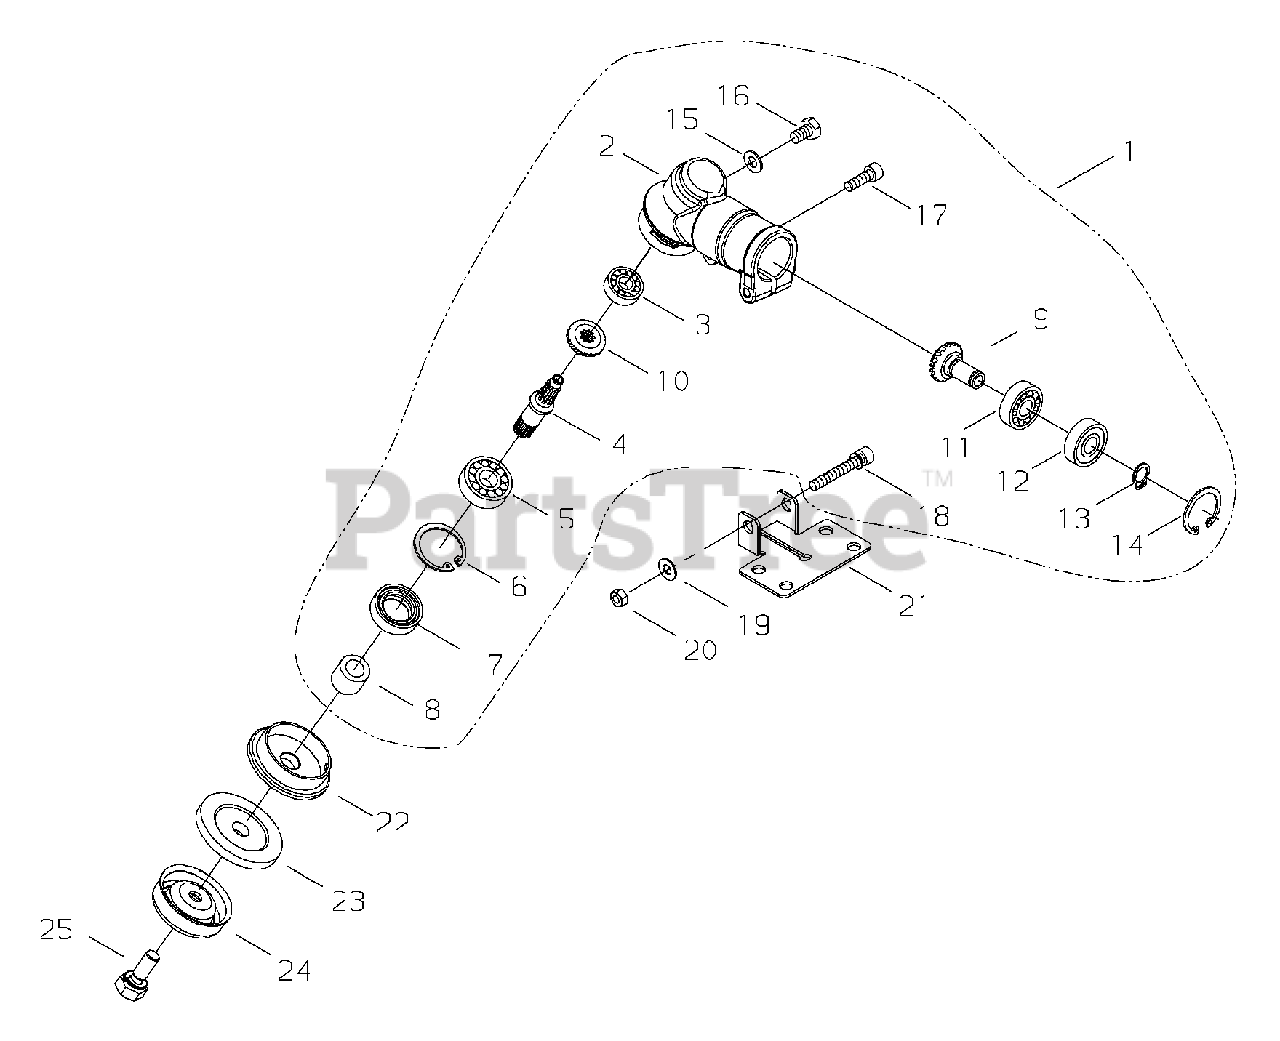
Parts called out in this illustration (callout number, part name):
1	GEAR CASE ASSY
2	HOUSING, GEAR CASE
3	BEARING, BALL 626 MOS
4	SHAFT, GEAR
5	BEARING, BALL 6000 MOS
6	RING, SNAP Ø26
7	SEAL, OIL
8	SPACER
9	GEAR, PINION
10	GEAR, BEVEL
11	BEARING, BALL 609 MOS
12	BEARING, BALL 609Z MOS
13	RING, SNAP Ø9
14	RING, SNAP Ø24
15	WASHER 6.5×11.5×0.8
16	BOLT M6×10
17	BOLT M5×10
18	BOLT M5×40
19	WASHER 5 MM
20	NUT M5
21	PLATE, SHIELD MOUNTING
22	PLATE, ADAPTOR - UPPER
23	PLATE, ADAPTOR - LOWER
24	GUARD, BOLT
25	BOLT M7×20
